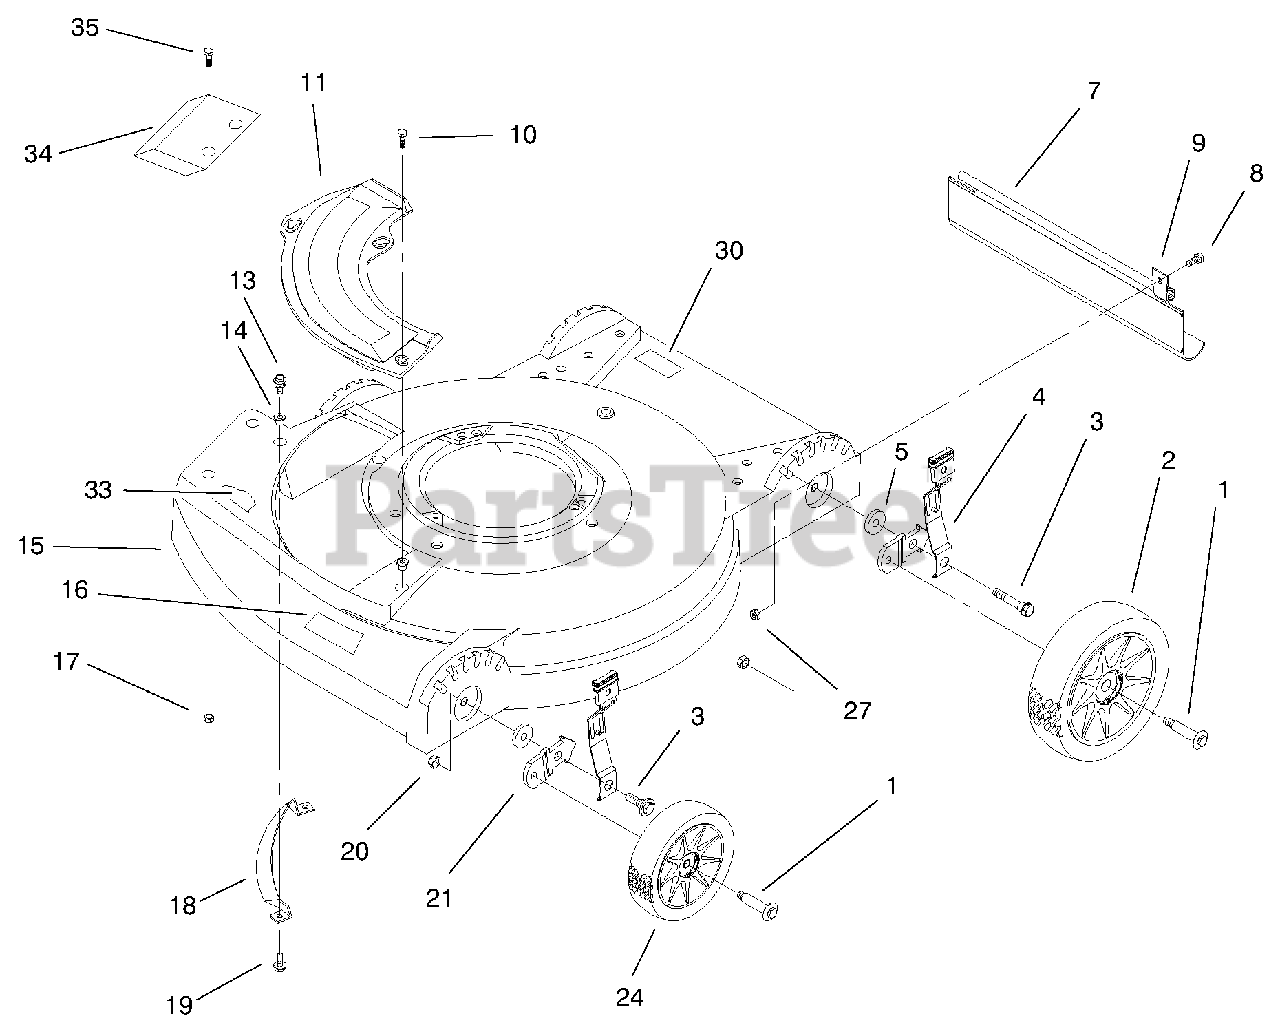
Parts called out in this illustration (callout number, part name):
1	Bolt-Wheel
2	ASM-Wheel & Tire
3	Bolt-Ajustment
4	Knob & Spring
7	Shield-Trailing
8	Screw-HH
9	Clamp-Rod
10	Screw-HH
11	Plate-Cover
13	Screw-Sems
14	Grommet-Plastic
15	Hsg-Commercial 21" Int'l
16	Decal-Deck 550c
17	Nut-Lock
18	Toe Bar 21
19	Screw-HWH
20	Nut-Lock
21	Bracket-Height
24	Wheel & Tire
27	Nut-Lock
30	Decal-Danger
33	Decal-Deflector Danger
34	Guard-Plate
